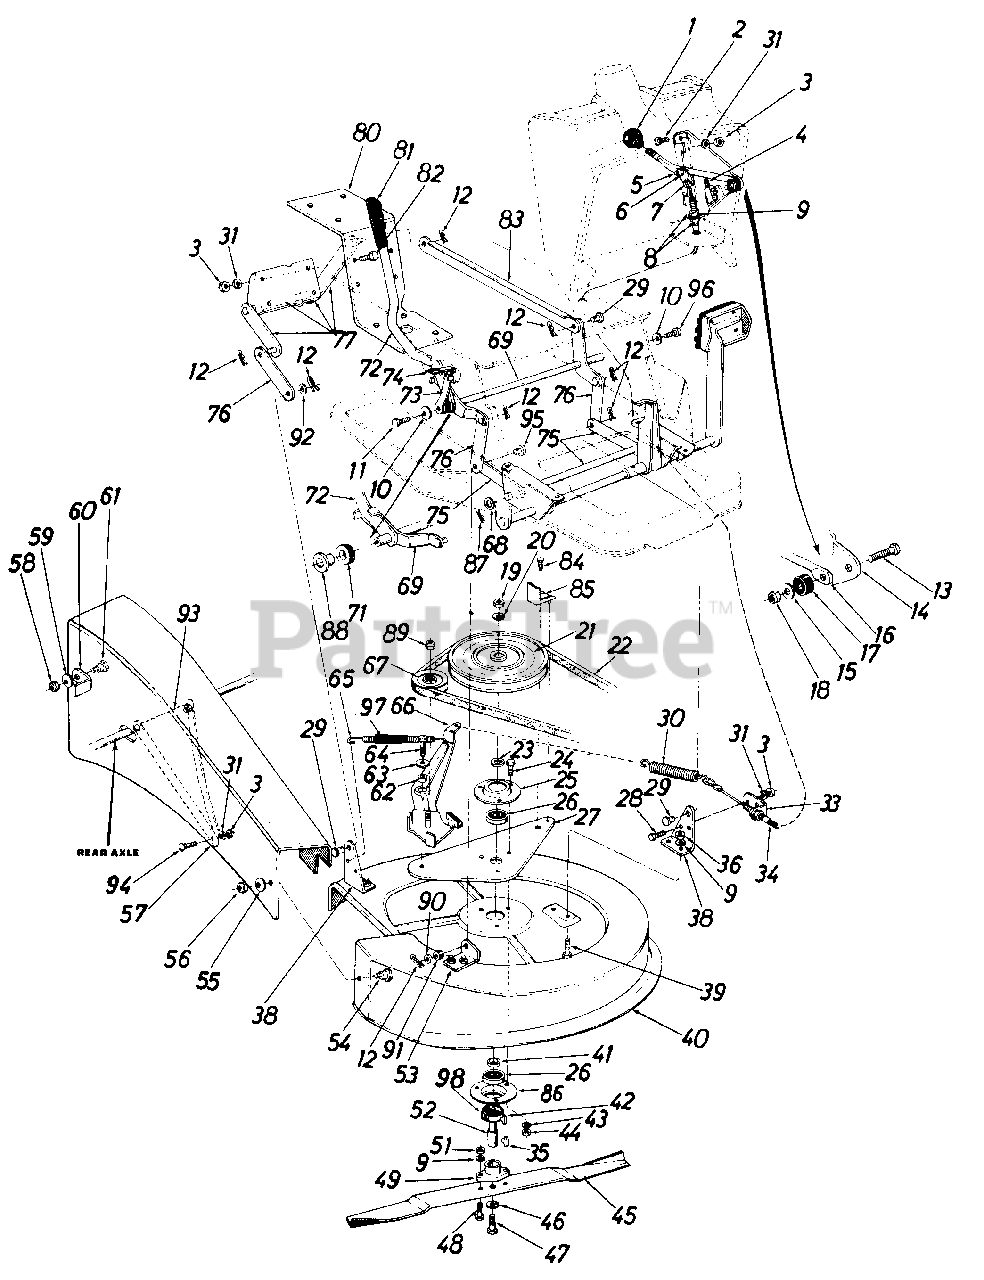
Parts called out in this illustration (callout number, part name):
1	Ball Knob
2	Truss Mach. Scr. 1/4-20 x .50" Lg.
3	Hex Nut 1/4-20 Thd.
4	Safety Switch
5	Weld Pin .250 Dia. x .62" Lg.
6	Push Cap .250 Dia.
7	Clevis
8	Hex Jam Nut 5/16-24 Thd.
9	L-Wash. 5/16" Scr.
10	Bell-Wash. .400 I.D. x 1.110 O.D.
11	Hex Wash. Hd. Self-Tap Scr. 3/8-16 x 1.25" Lg.
12	Internal Cot-Pin 1/2" Dia.
13	Hex Scr. 1/4-20 x 1.25" Lg.
14	Deck Clutch Control Brkt.
15	Fl-Wash. .280 I.D. x .750 O.D. x .063
16	Blade Clutch Lever
17	Rubber Washer
18	Hex Cent. L-Nut 1/4-20 Thd.
19	Hex Nut 5/8-11 Thd.*
20	L-Wash. 5/8" Scr.
21	Deck Pulley
22	"V"-Belt "A" or 1/2" x 54" Lg.
23	Spacer
24	Hex Sems Scr. 5/16-18 x 1.00" Lg.
25	Bearing Housing
26	Ball Brg. .787 I.D. x 1.850 O.D.
27	Deck Belt Guard Plate
28	Hex Sems Scr. '/4-20 x .75" Lg.*
29	Lift Brkt. Pin Special
30	Extension Spring .88 O.D. x 4.0" Lg.
31	L-Wash. 1/4" Scr.
33	Cable Bracket
34	Clutch Control Cable 26.88" Lg.
35	#6 Hi-Pro Key 5/32 x 5/8" Dia.
36	Hex Nut 5/16-18 Thd.
38	Deck Bracket
39	Carriage Bolt 5/16-18 x .75"
42	#61 Hi-Pro Key 3/16 x 5/8" Dia.
43	L-Wash. 5/16" Scr.
44	Hex Nut 5/16-18 Thd.
45	26" Blade
46	L-Wash. 3/8" Scr. H.D.
47	Hex Scr. 3/8-24 x 1.50" Lg. H.T.
48	Hex Scr. 5/16-24 x 1.00" Lg. H.T.-Special
49	Blade Adapter Kit
51	Hex Nut 5/16-24 Thd.
52	Blade Spindle
53	Deck Bracket Chute
54	Shld. Scr. .500 Dia. x .170 Lg.
55	Fl-Wash. .385 I.D. x .88 O.D.
56	Hex Cent. L-Nut 3/8-16 Thd.
57	Chute Ass'y.
58	Hex Ins. L-Nut 5/16-18 Thd.
59	Bell. Wash. .345 I.D. x .88 O.D.
60	Chute Pivot Brkt.
61	Shld. Scr. .437 I.D. x .180" Lg.
62	Spacer .315 I.D. x .75 O.D. x .370 Lg.
63	Fl-Wash. .344 I.D. x 1.12 O.D. x .12
64	Hex Scr. 5/16-18 x 1.00" Lg.
65	Extension Spring
66	Deck Idler Brkt. Ass'y.
67	V-Idler Pulley
68	Fl-Wash. .630 I.D. x .930 O.D. x .060
69	Lift Handle Shaft Ass'y.
71	Rubber Wash.
72	Lift Handle
73	Lift Handle Stop
74	Height Adj. Knob
75	Lift Arm Shaft Ass'y.
76	Deck Link
77	Lift Pivot Brkt. Ass'y.
80	Seat Support Ass'y.
81	Grip
82	Hex Sems Scr. 1/4-20 x 1.00" Lg .
83	Connecting Link
84	Hex Wash. Hd. Self-Tap Scr. 5/16-24 x .75" Lg.
85	Belt Keeper Ass'y.
87	Cotter Pin 3/32" Dia. x .75"
88	Flange Brg. .62 I.D. x .87 O.D. x .63" Lg .
89	Hex Ins. L-Nut 3/8-24 Thd.
90	Fl-Wash. .530 I.D. x .940 O.D. x .050
91	Rubber Wash. .531 I.D. x 1.00 O.D. x .120
92	Fl-Wash. .531 I.D. x .93 O.D. x .090
93	Chute Baffle
94	Carriage Bolt 1/4-20 x .50"
95	Clevis Pin .500
96	Self-Tap Scr. 3/16-16 x 1.0" Lg.
97	Shrink Tube
98	Bearing Shield
